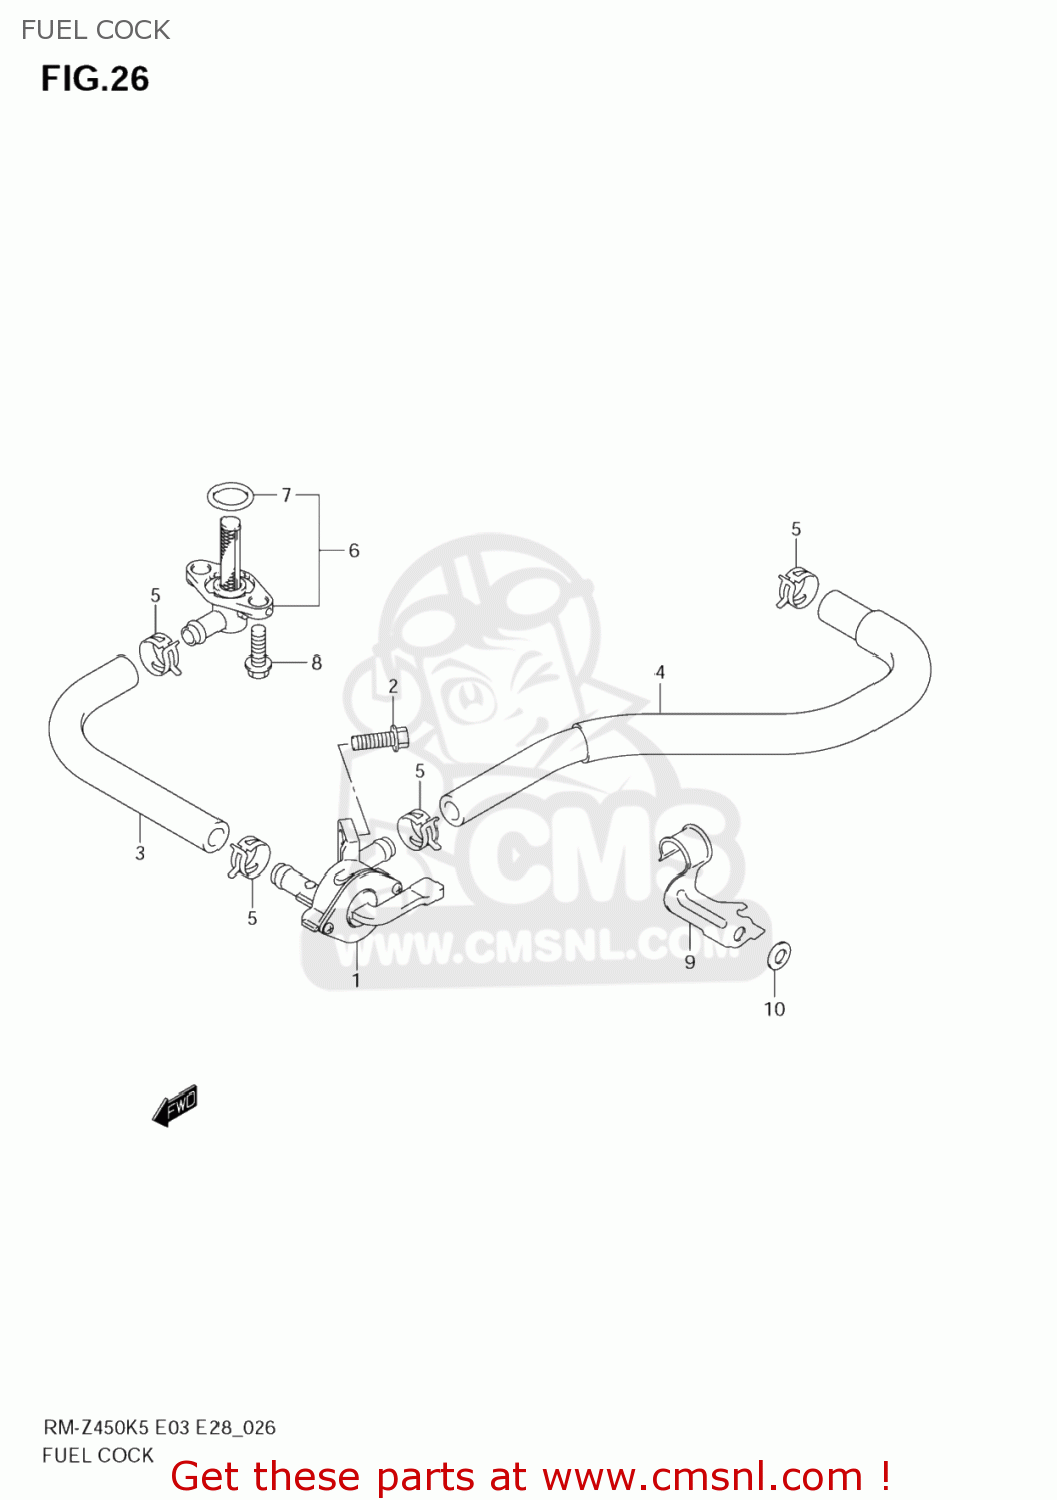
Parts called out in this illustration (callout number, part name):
1	COCK ASSY,FUEL
2	BOLT(6X16)
3	HOSE,FUEL NO.1
4	HOSE,FUEL NO.2
5	CLIP
6	JOINT ASSY,FUEL HOSE
7	O RING,FUEL HOSE JOINT
8	BOLT(6X16)
9	CLAMP,FUEL HOSE
10	WASHER
